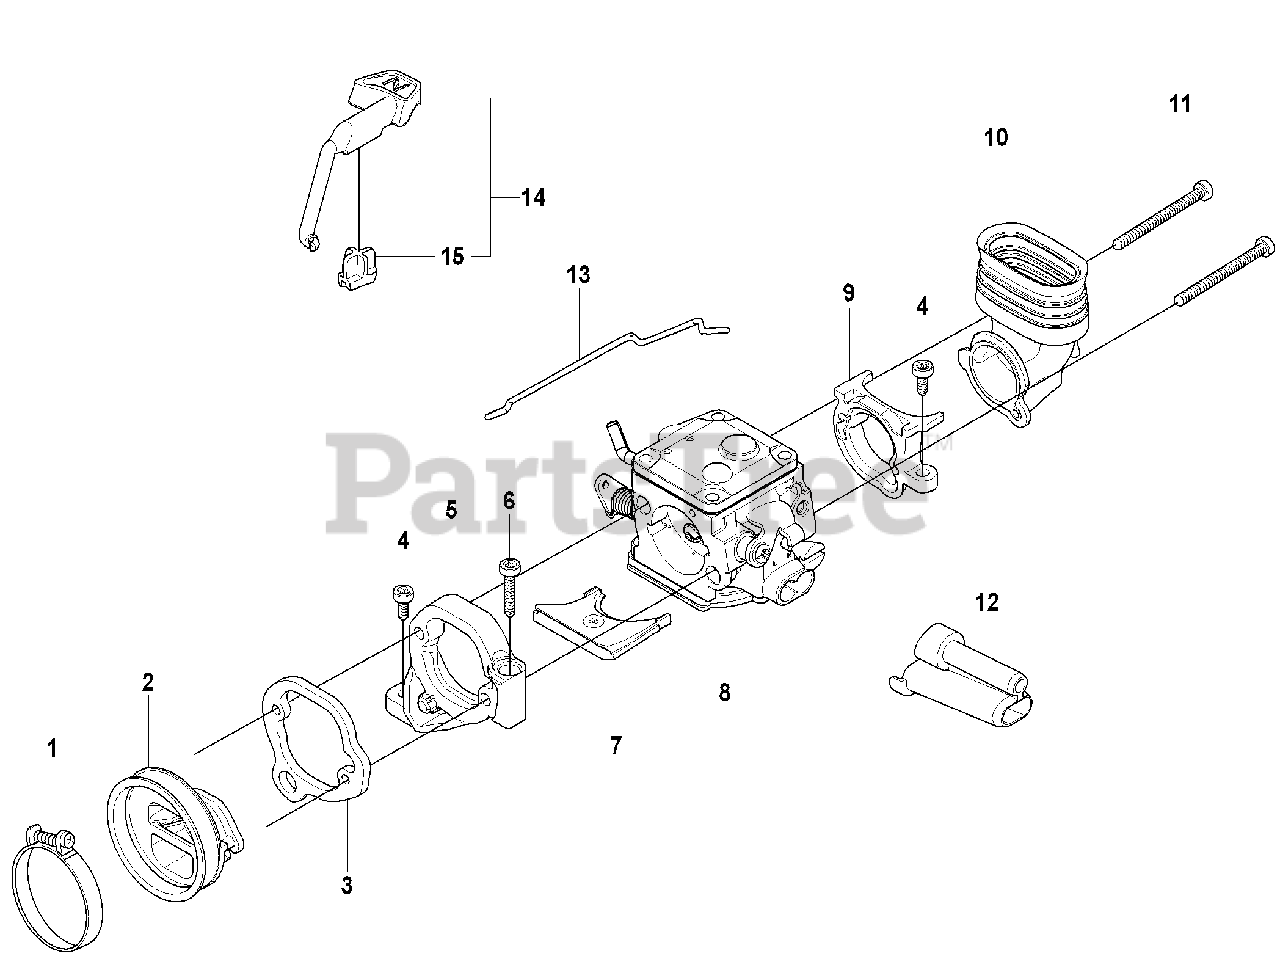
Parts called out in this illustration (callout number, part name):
1	HOSE CLAMP
2	INLET PIPE
8	CARBURETTOR
10	INLET BEND
11	SCREW
12	CHISEL GUIDE
13	THROTTLE ROD
14	CHOKE
15	WEAR PROTECTION
